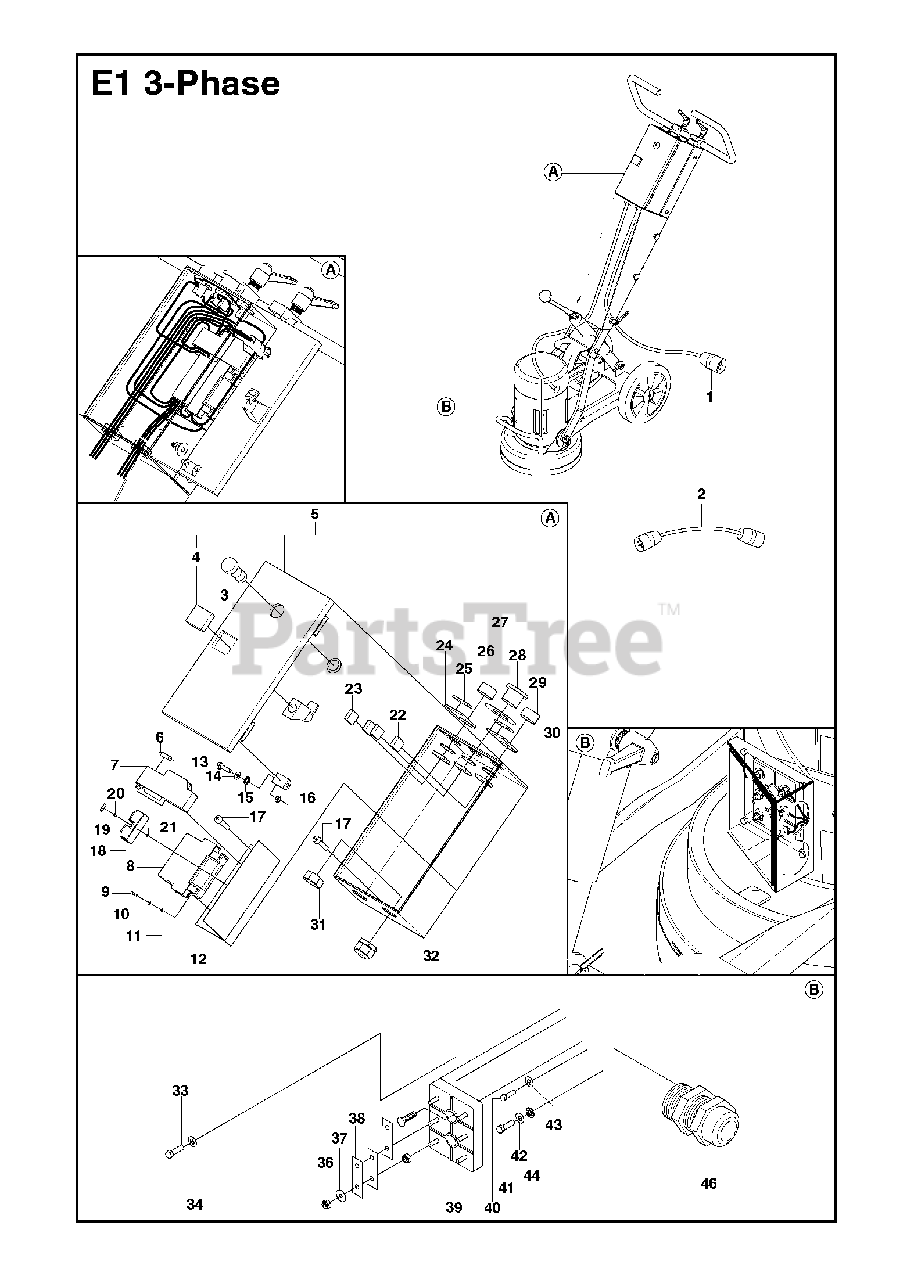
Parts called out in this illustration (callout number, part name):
11	HEXAGON LOCKING NUT
13	SCREW EHHM
21	HEXAGON LOCKING NUT
